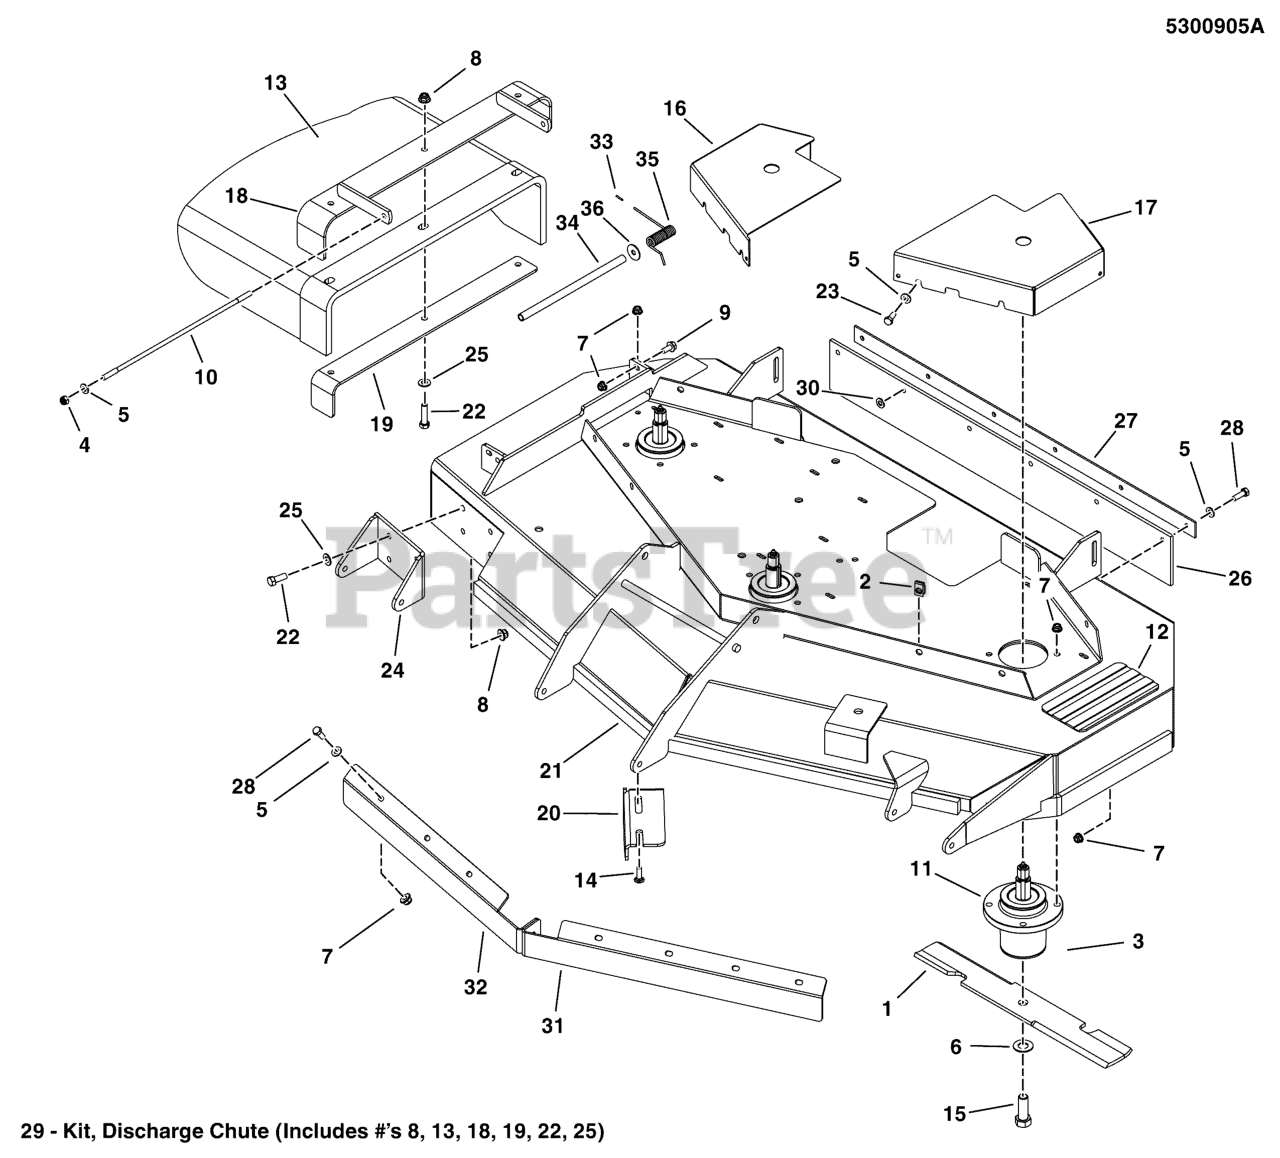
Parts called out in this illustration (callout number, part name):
1	BLADE, 18 X .25 X 2.5, 1 X 3.5 (SET OF THREE)
1	BLADES, SET OF THREE (3); 16.25 X.25 X 2.5, 1 X 3.5
2	BODY CLIP, 5/16-18-7GA MATERIAL
3	BOLT, Flange Head, 5/16-18 x 1-1/4
4	NUT, 5/16-24 HEX NYLON LOCK
5	WASHER, 5/16" SAE
6	WASHER, BLADE BOLT, 9/16" F436, CZ
7	NUT, 5/16-18 HEX NYLOCK FLANGE NUT
8	NUT, 3/8 - 16 HEX NYLOCK FLANGE
9	BOLT, 5/16-18 X 3/4 GD5
10	ROD, MOUNT, CHUTE, 61, CZ
10	ROD, 5/16 X 13.75, TBE, CZ
11	SPINDLE, ASSM, ALUMINUM - 5.25
12	SAFETY WALK, 4.00 X 7.50
13	CHUTE, DISCHARGE, BEND RUBBER, 44/48/52 (5100842)
13	CHUTE, DISCHARGE, RUBBER, 61/72, BENT
14	BOLT, 5/16-18 X 3/4, CARRIAGE, GD5, CZ
15	BOLT, 5/8-11 X 1-3/4 GD8
16	GUARD, 52" DECK - RH - RED
16	GUARD, 48 DECK - RH -RED
17	GUARD, 52" DECK - LH - RED
17	GUARD, 48 DECK - LH -RED
18	WELD, FRAME, CHUTE, 61 / 72 - RED
18	WELD, FRAME, CHUTE, 48/52 - BLK
19	SUPPORT, DISCHARGE CHUTE, 61/72 - BLK
19	SUPPORT, DISCHARGE CHUTE, 44/48/52 - BLK
20	PLATE, DEFLECTOR - BLK
20	PLATE, DEFLECTOR, 52 DECK - BLK
21	DECK SHELL W/ DECALS, 48 - S150X
21	DECK SHELL W/ DECALS, 52 - S150X
21	DECK SHELL W/ DECALS, 52 - S150XCE
22	BOLT, 3/8-16 X 1-1/4" GD5 CZ
23	BOLT, 5/16-18 X 3/4 GD5
24	PLATE, BRACKET, ANTI SCALP, RH - 61 -RED
25	WASHER, 3/8 SAE
26	FLAP, STRIPER, 48 DECK
26	FLAP, STRIPER, 61" DECK, IS3100, S200X
27	PLATE, SUPPORT, 48 - BLK
27	PLATE, SUPPORT - BLKV
28	BOLT, 5/16-18 X 1" GRD5 YZ
29	KIT, DISCHARGE CHUTE, 61/72, SNP PRO (SV)
29	KIT, DISCHARGE CHUTE
30	5/16" PUSH-ON NUT RETAINER, STL, CZ
31	BAFFLE, FRONT DISCHARGE, LH,S150XCE, RED
32	BAFFLE, FRONT DISCHARGE, RH,S150XCE, RED
33	CAP, PROTECTOR, .120 ID
34	SPACER, TORSION SPRING, 9.63 LG
35	SPRING, TORSION
36	WASHER, 5/16" Fender
